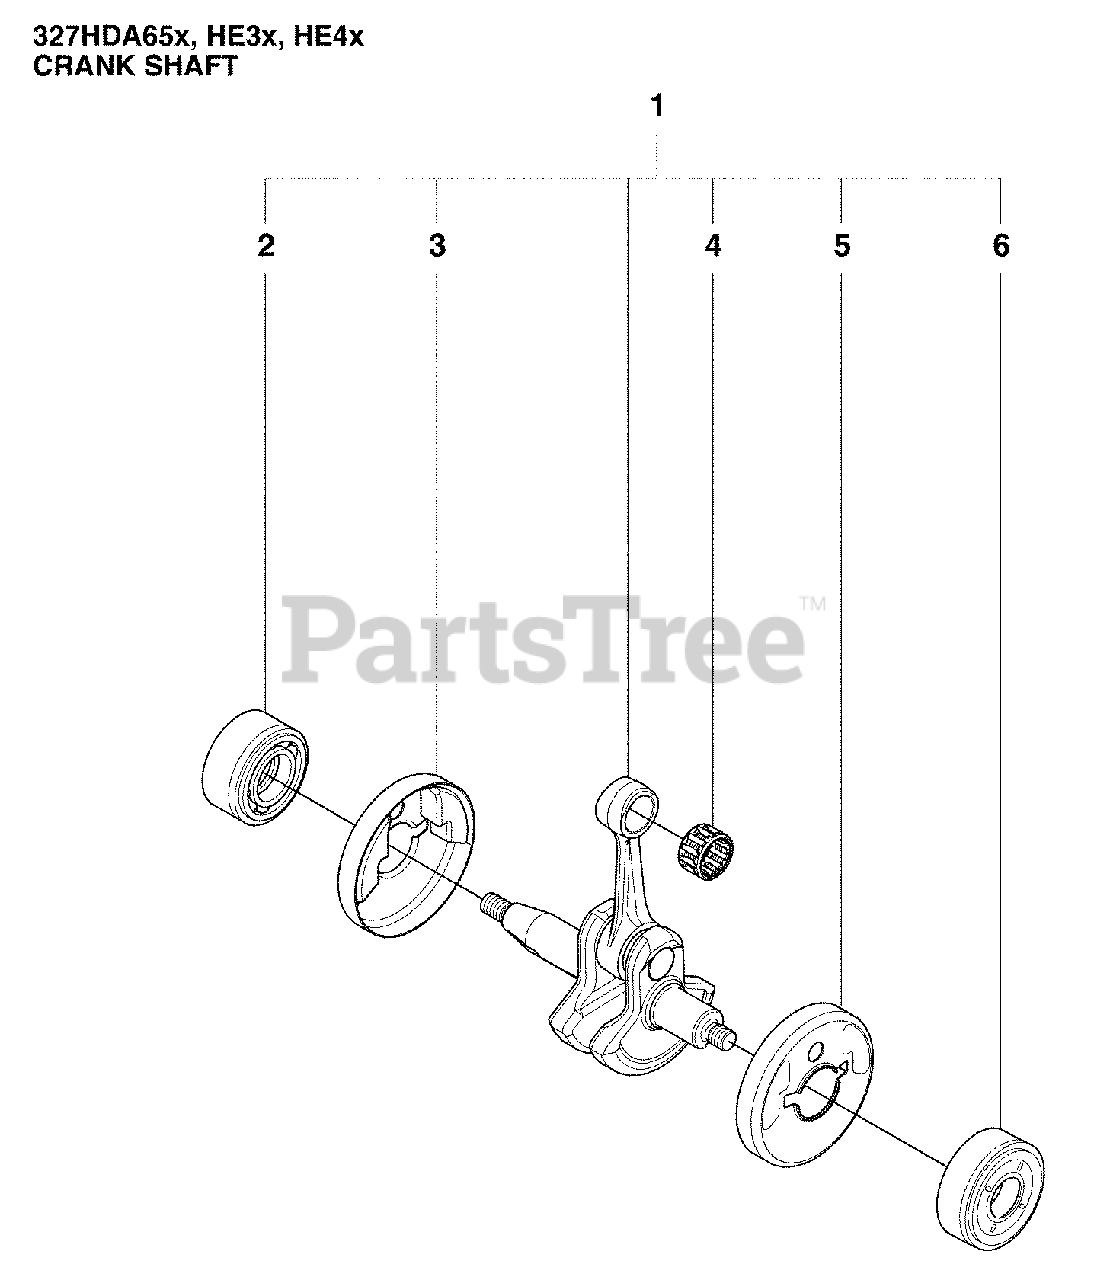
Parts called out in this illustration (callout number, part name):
1	Crankshaft
2	Bearing Cap
6	Bearing Cap
